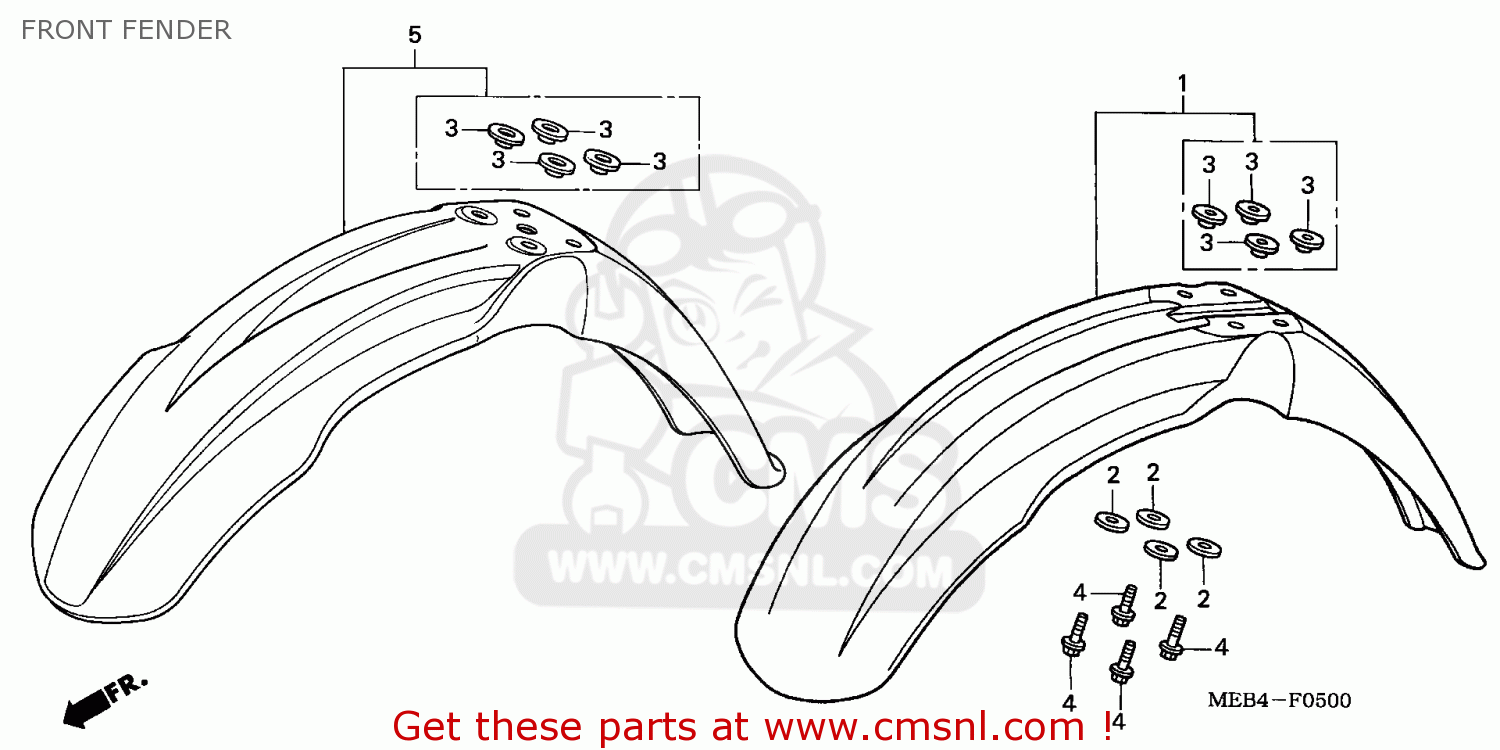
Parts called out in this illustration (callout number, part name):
1	SUB ASSY F*R254R*
2	WASHER,FENDER MT.
3	COLLAR FR FENDER
4	BOLT,FLANGE,SH,6X16
